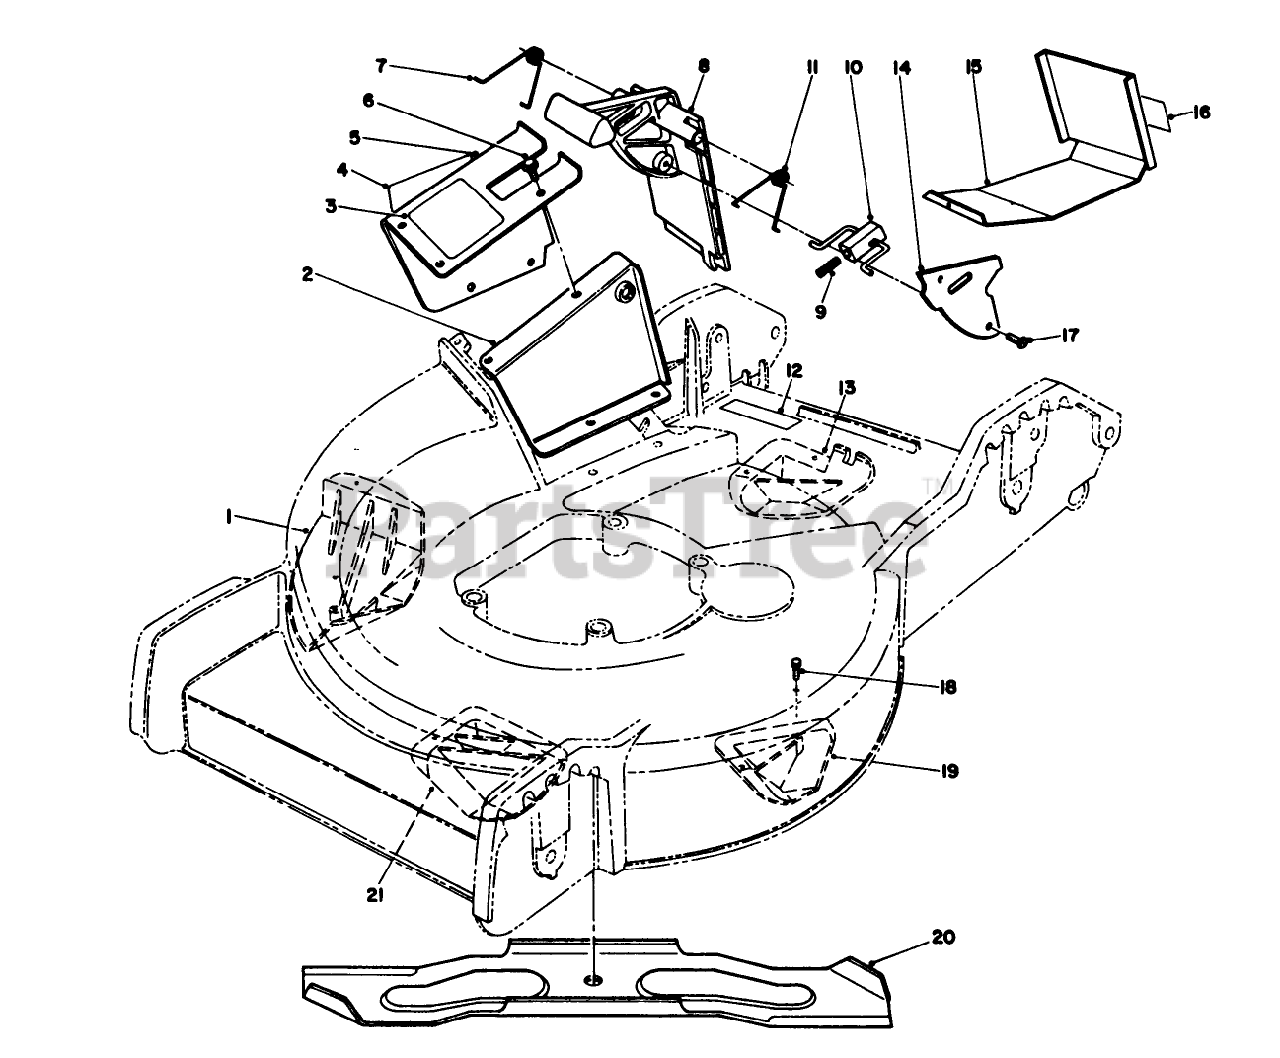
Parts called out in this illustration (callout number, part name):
1	KICKER
2	Tunnel-Inner
3	DECAL - CAUTION DOOR
4	DECAL-DANGER
5	Tunnel-Outer (Incl. Ref. #3 & 4)
6	SCREW-HWH
7	SPRING-DOOR, RH
9	SPRING-COMPRESSION, LATCH
10	LATCH-DOOR
11	LH DOOR SPRING
12	DECAL - CAUTION
13	KICKER
14	DOOR COVER
15	Discharge Plug Assembly (Incl. Ref. #16)
16	DECAL - WARNING
18	SCREW-PPH
19	KICKER
20	Blade-18"
21	KICKER
